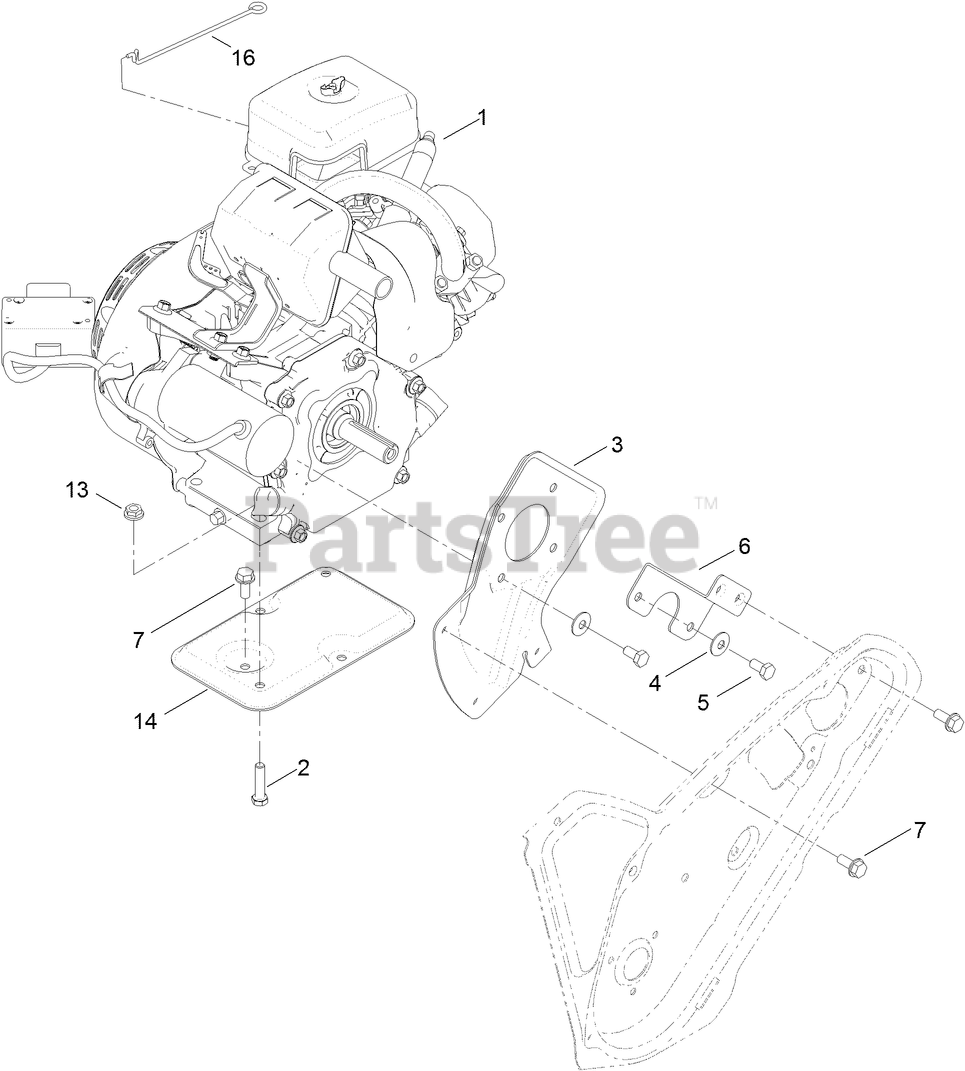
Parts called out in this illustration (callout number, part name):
1	ENGINE-168FS-1
2	SCREW-HH
3	PLATE-ENGINE, PTO
4	WASHER-BELLEVILLE
5	SCREW-HHF
6	SUPPORT-ENGINE, SIDE
7	SCREW-THD ROLL, HWH
13	NUT-HF
14	SUPPORT-ENGINE
